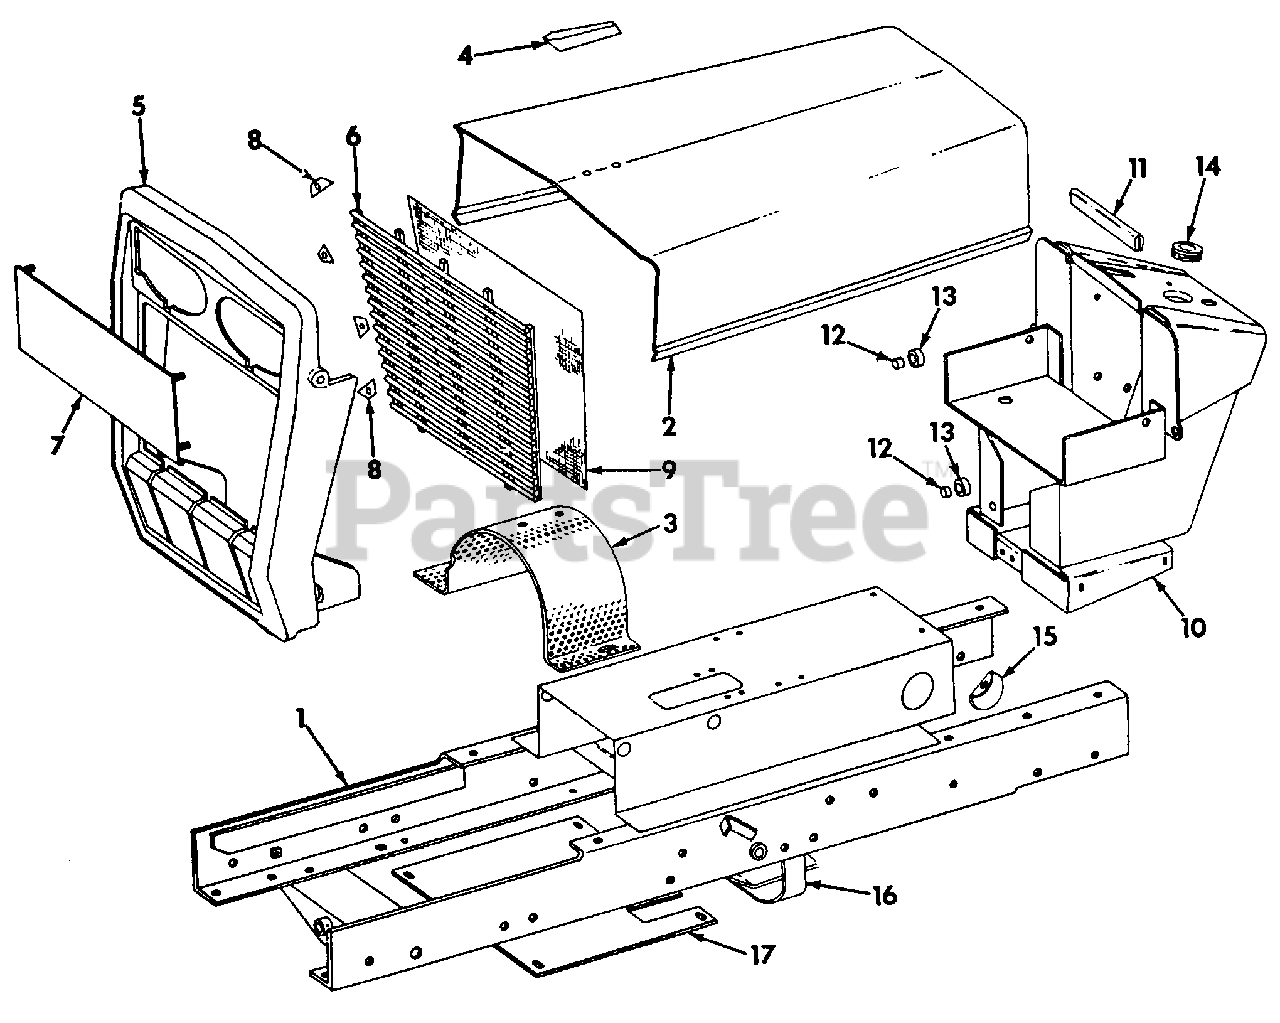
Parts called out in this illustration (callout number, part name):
1	Frame Assy
2	Hood Assy
3	Shield, Clutch
4	Product Graphic, Hood Ornament
5	Housing, Grille
6	Grille
7	Strip Assy, Grille Panel
8	Strip, Grille Panel Clamp
9	Screen, Grille
10	Pedestal Assy
11	Bumper, Hood
12	Spacer, Hood Roller Lock
13	Roller, Hood Lock, Rubber
14	Grommet, Instrument Panel
15	Plate, Neutral Adj Cover
16	Guard Assy, Suction Tube
17	Sheet, Bottom Clutch Shield
